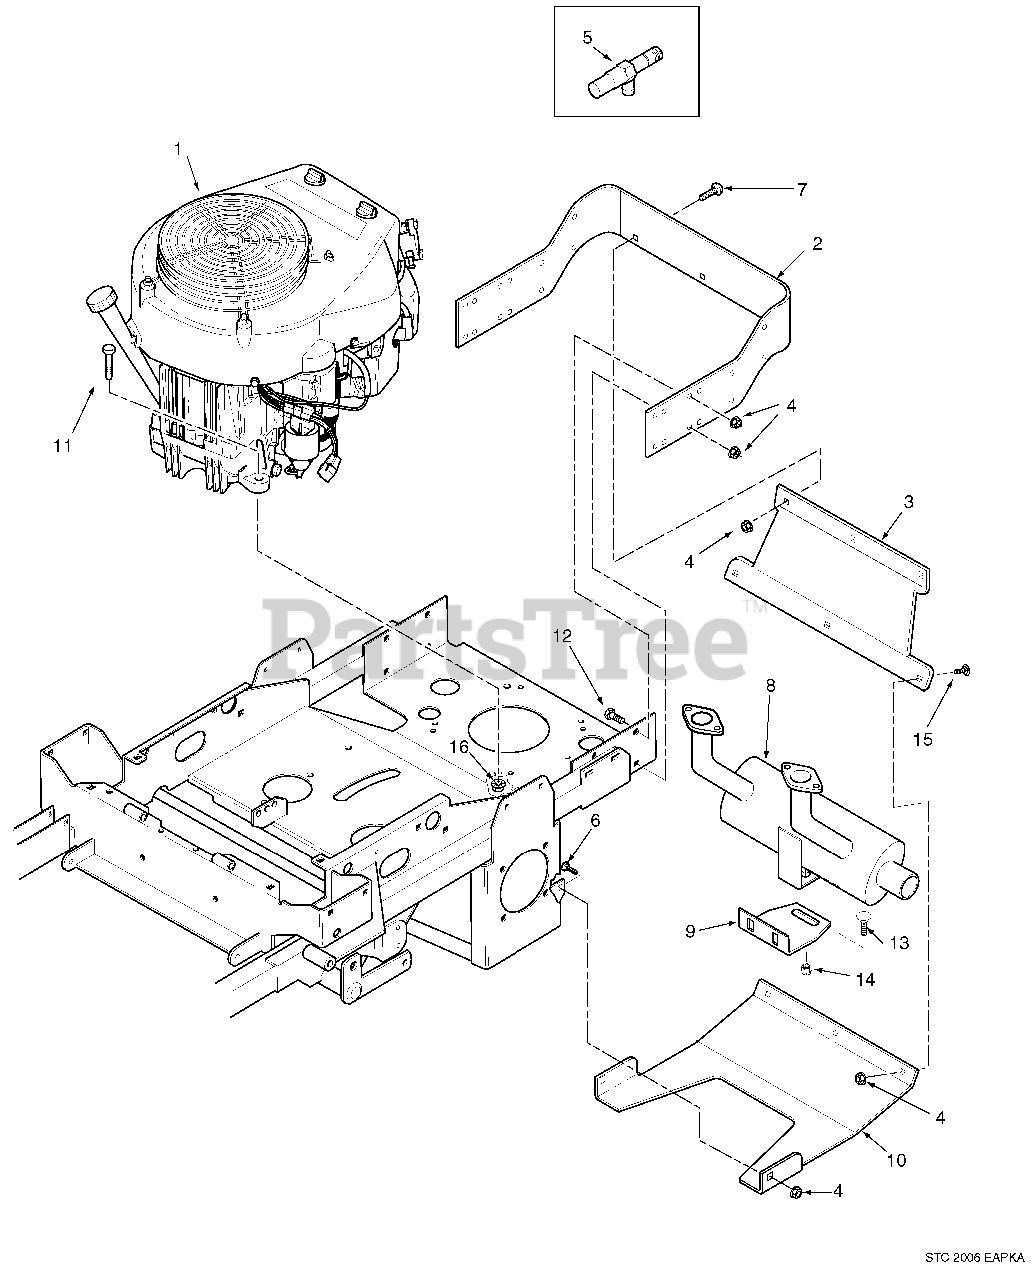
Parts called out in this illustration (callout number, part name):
1	Engine
2	Bumper, Rear
3	Shield, Rear
4	Nut, Serr. Flange 3/8-16
5	Extension, Oil Drain 2.3"
5	Extension, Oil Drain 4"
6	Bolt, Carr. 3/8-16 x 1"
7	Bolt, 3/8-16 x 1" Torx
7	Bolt, Hex Head 3/8-16 x 1-1/4"
8	Muffler
9	Bracket, Muffler
10	Plate, Skid
11	Bolt, Hex Head 5/16-18 x 1-1/2"
12	Bolt, Hex Head 3/8-16 x 1"
13	Bolt, Hex Head 5/16-18 x 3/4"
14	Nut, Serr. Flange 5/16-18
15	Bolt, Carr. 3/8-16 x 3/4"
16	Nut, Serr. Flange 5/16-18
